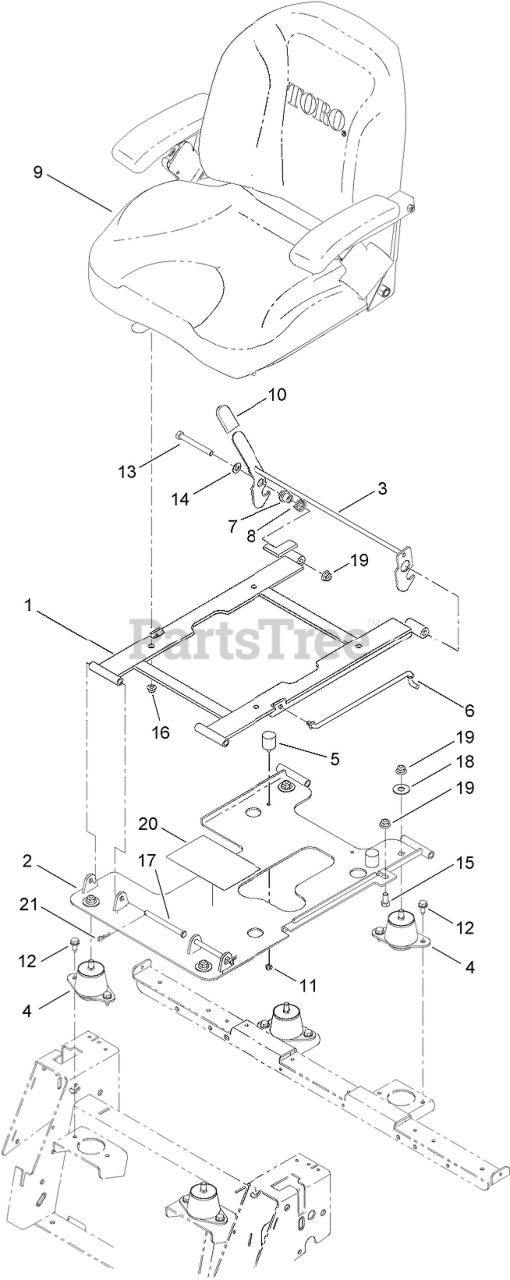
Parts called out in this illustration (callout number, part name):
1	SEAT PAN ASM
2	SEAT BASE ASM
3	LATCH ASM
4	ISOLATOR-SEAT
5	Bumper
6	ROD-PROP
7	BUSHING-LATCH, SEAT
8	SPRING-TORSION
9	SEAT ASM
10	GRIP-LEVER
11	NUT-LOCK, NI
12	SCREW-HWHTF
13	SCREW-HH
14	WASHER-FLAT
15	SCREW-HH
16	NUT-HF, NI
17	PIN-CLEVIS
18	WASHER-FLAT
19	NUT-HF, NI
20	DECAL-MAINTENANCE
21	PIN-COTTER
